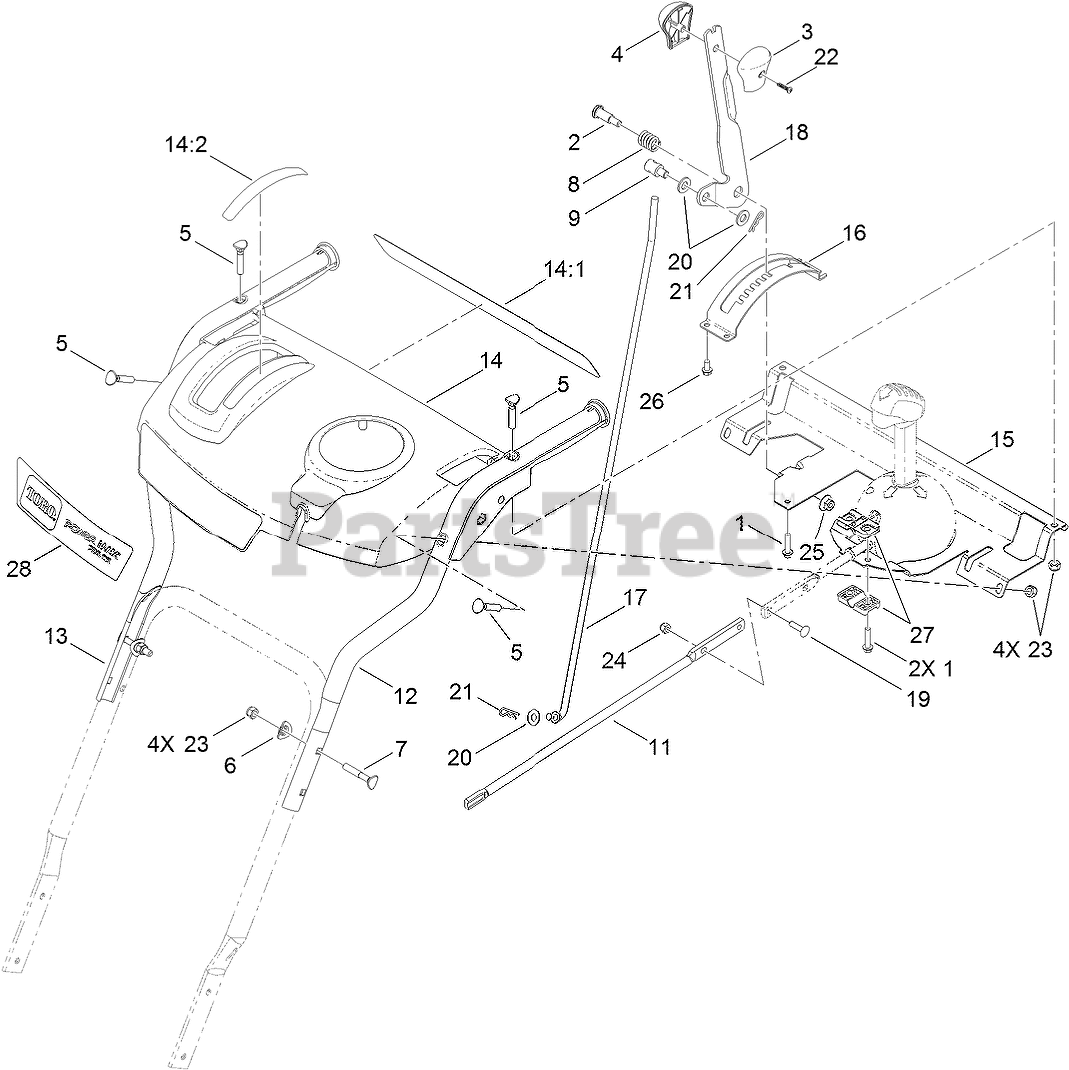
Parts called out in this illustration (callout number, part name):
1	SCREW-PLASTITE
2	SCREW-SHOULDER
3	KNOB-SHIFT, LH
4	KNOB-SHIFT, RH
5	SCREW-HANDLE
6	WASHER
7	SCREW-HANDLE
8	SPRING-COMPRESSION
9	TRUNNION-ROD
11	ROD-CHUTE, FRONT
12	HANDLE-UPPER, LH
13	HANDLE-UPPER, RH
14	PANEL-CONTROL, MASTER
14:1	DECAL-SAFETY
14:2	DECAL-CONTROL, SPEED
15	SUPPORT-PANEL, CONTROL
16	MOUNT-SELECTOR, SPEED
17	ROD-SELECTOR, GEAR
18	SELECTOR-SPEED
19	SCREW-CARR
20	WASHER-FLAT
21	PIN-COTTER
22	SCREW-PPH
23	NUT-LOCK, NI
24	NUT-LOCK, NI
25	NUT-HF
26	SCREW-PLASTITE
27	SUPPORT-ROD
28	DECAL-MODEL
